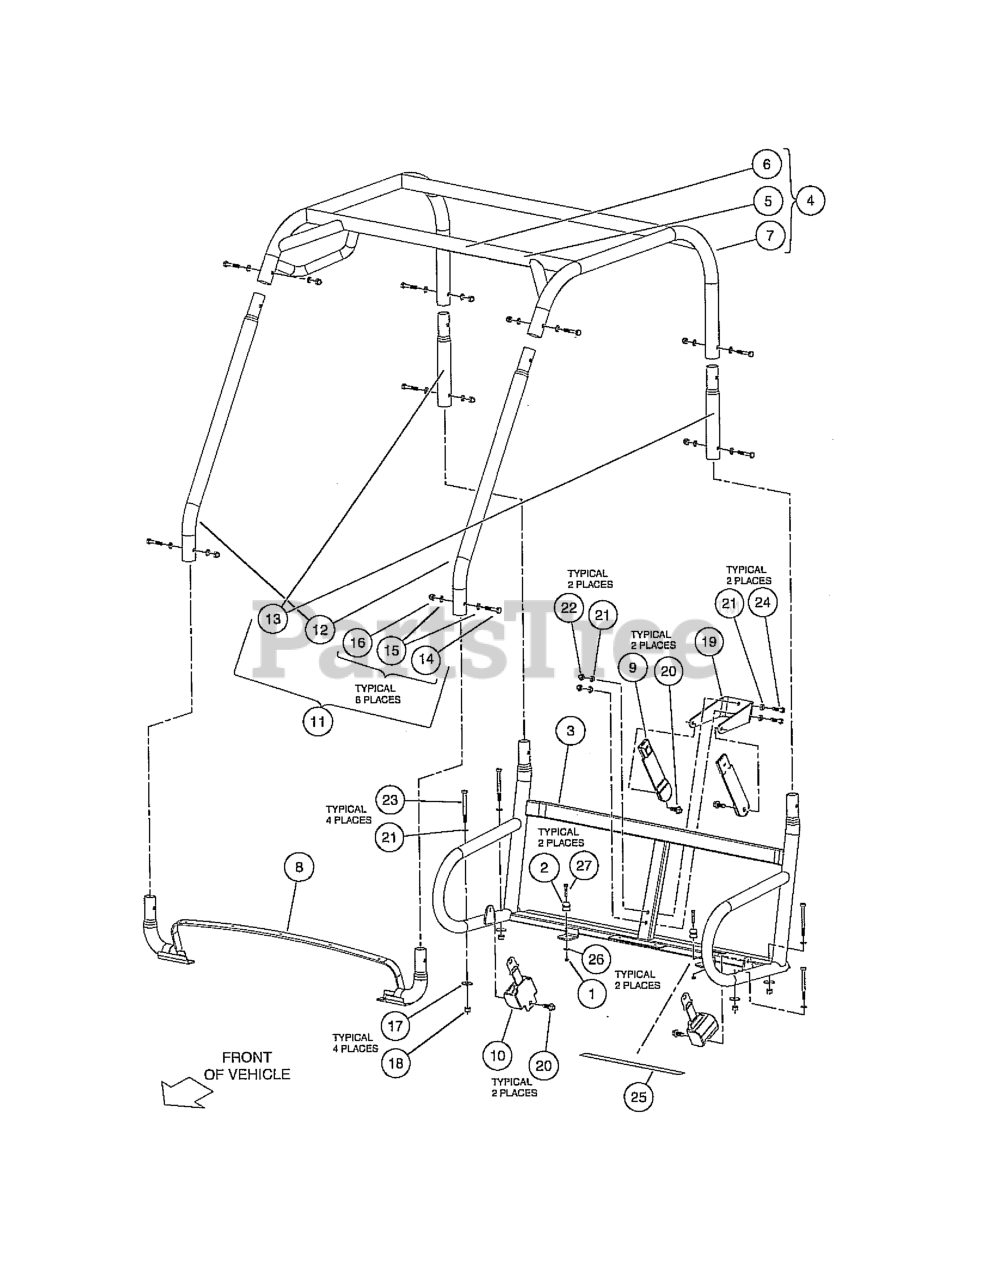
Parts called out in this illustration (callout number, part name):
1	LOCKNUT, M6-1.00 NYLON INSERT
2	SEAT HOLDER BASE
3	WELDMENT, SUPP, SEAT, ROPS
4	WELDMENT, TOP, ROPS
5	DECAL, WARNING UNDER 16
6	DECAL, WARNING-CERTIFIED ROPS
8	WELDMENT, SUPP, COWL, ROPS
9	BUCKLE, SEAT BELT W/ SLEEVE
10	RETRACTOR, SEAT BELT
12	TUBE, SUPP, FRONT, ROPS
13	TUBE, SUPP, REAR, ROPS
15	WASHER, HARD, M10, ZN-NI/BLK
16	NUT, HEX CAP, M10, ZN-NI/BLK
17	WASHER HARD, M10
18	NUT FLG M10 X 1.5 MECH DEF
19	BRKT, SEATBELT, BOLT-ON
20	SCREW,M12X1.75X30 THD FORM BLK
21	WASHER, HARD, M10, ZN-NI/BLK
22	NUT, HEX CAP, M10, ZN-NI/BLK
23	BOLT, M10 X 100, ZN-NI/BLK
24	BOLT, M10 X 45, ZN-NI/BLK
26	WASHER 1/4 FLAT
